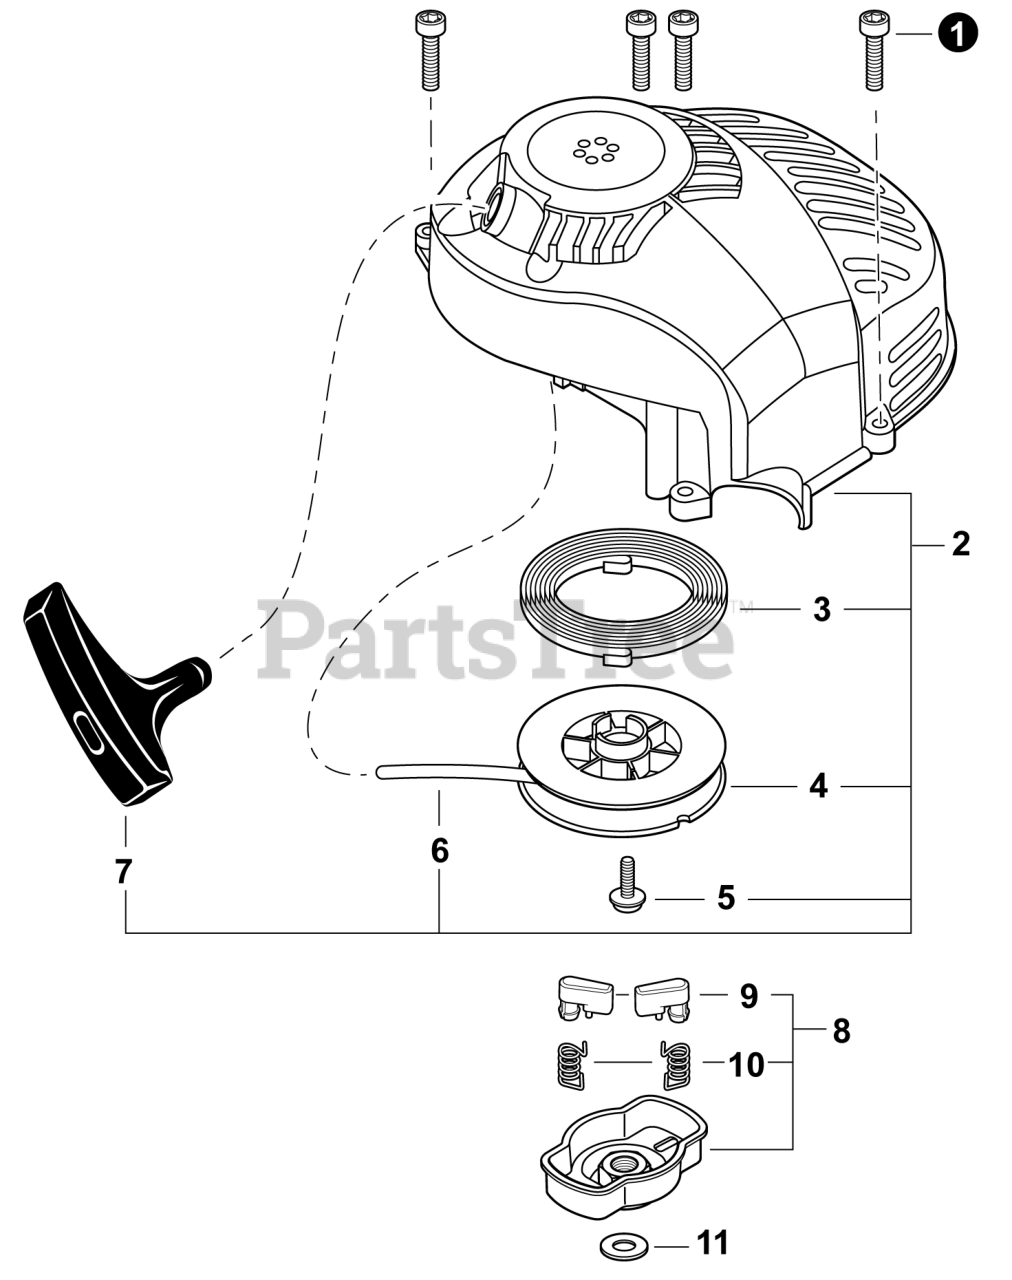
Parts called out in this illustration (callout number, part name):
1	BOLT, TORX 4×16
2	STARTER ASSY, RECOIL
3	SPRING, RECOIL
4	REEL, ROPE
6	ROPE, STARTER Ø3×850
7	GRIP, STARTER
8	PAWL ASSY, STARTER
9	PAWL, STARTER - BLACK
10	SPRING, RETURN
11	WASHER, SPRING 8
